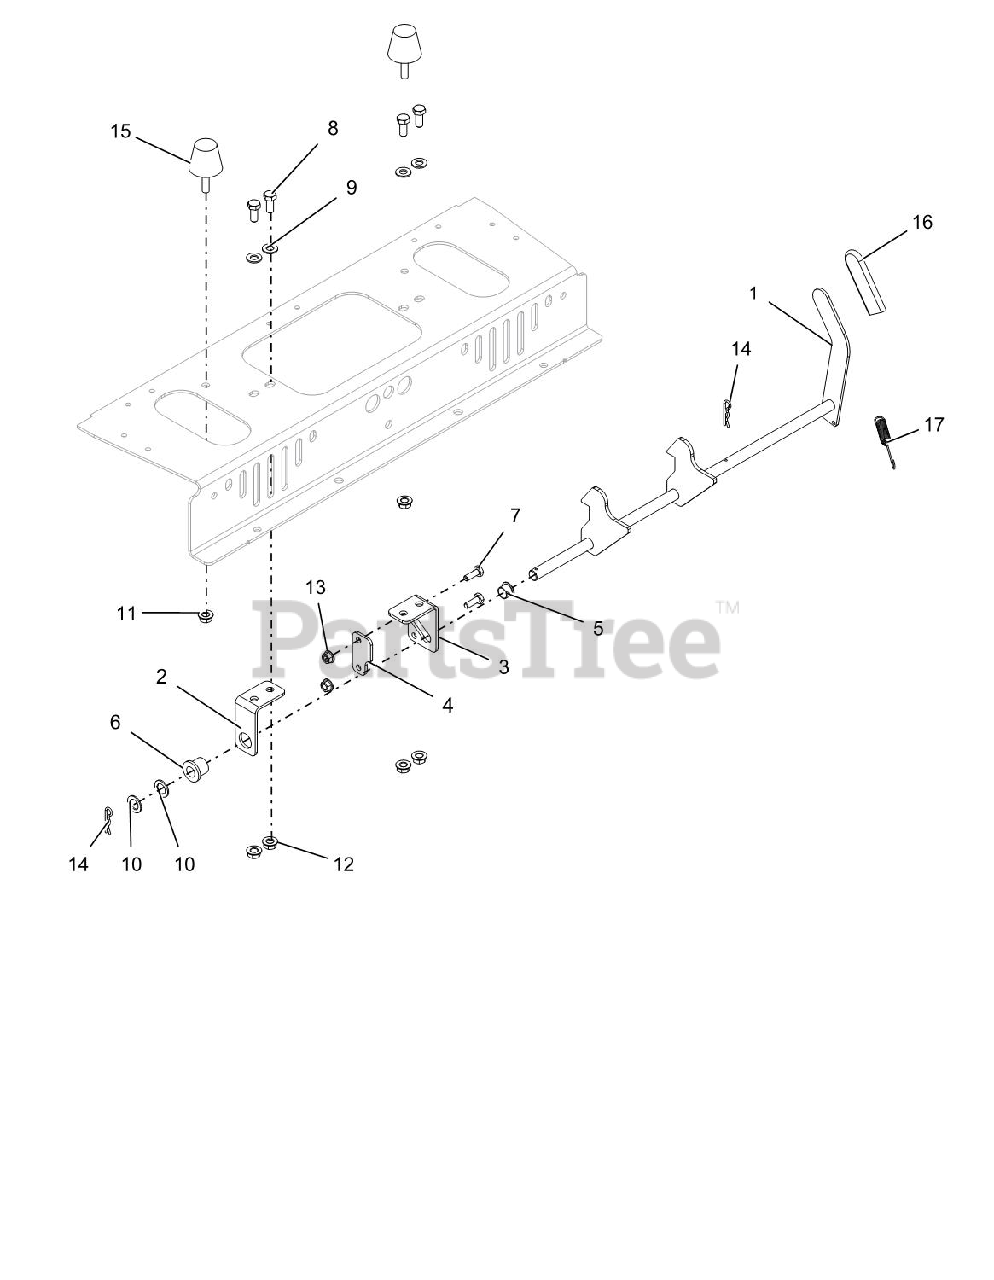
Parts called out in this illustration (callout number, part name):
1	WMT, SEAT LATCH
2	MOUNT, SEAT LATCH - RH
3	MOUNT, SEAT LATCH - LH
4	RETAINER-SEAT LATCH
5	BUSHING, POLYLINER - .50 SPLIT
6	BSHG, FLANGE .515 X .750 X .745 X 1.00 NYLON
7	BLT-HEX .25-20X.75 GR5 YWZC
8	BLT-HEX .31-18X.75 GR5 YWZC
9	WSHR-FL-STL.344X.688X.065YWZC
10	WSHR-FL-STL .520X.827X.062 YWZC
11	@NUT-SPNLK-FLG .312-18 YWZC
12	NUT, LK-TOP-FLG .312-18 YWZC
13	NUT, LK-TOP-FLG .25-20 YWZC
14	PIN-HAIR INT .08X.38X1.42 YWZC
15	BUMPER, STUD MOUNTED CONE SHAPED
16	GRIP-VINYL-YELLOW .125 x 1.0 x 3.0
17	SPRG, EXTENSION
